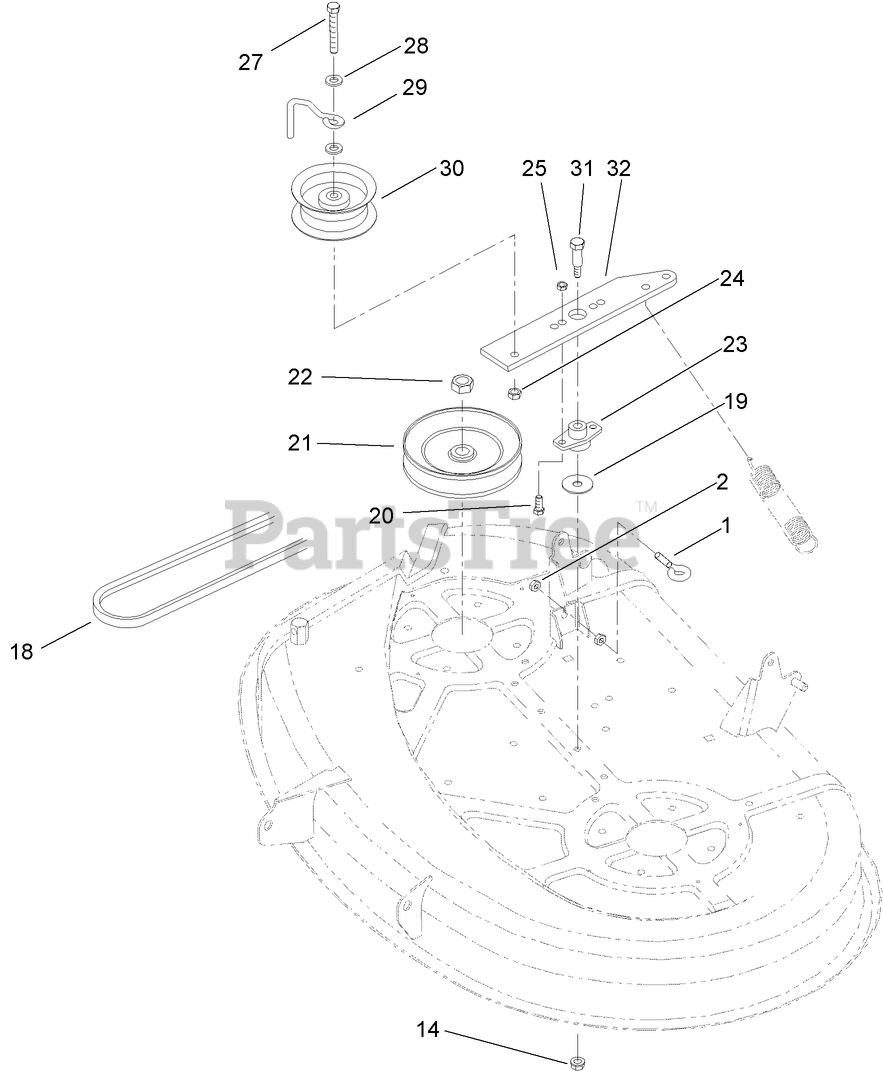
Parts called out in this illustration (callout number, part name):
1	EYEBOLT
2	NUT-JAM
14	NUT-LOCK, NI
18	V-BELT
19	WASHER-FLAT
20	SCREW-HH
21	PULLEY
22	NUT-HEX
23	BUSHING-ARM, IDLER
24	NUT-LOCK, NI
25	NUT-LOCK, NI
27	SCREW-HH
28	WASHER-FLAT
29	GUIDE-IDLER, BELT
31	SCREW-SHOULDER, HH
32	ARM-IDLER
